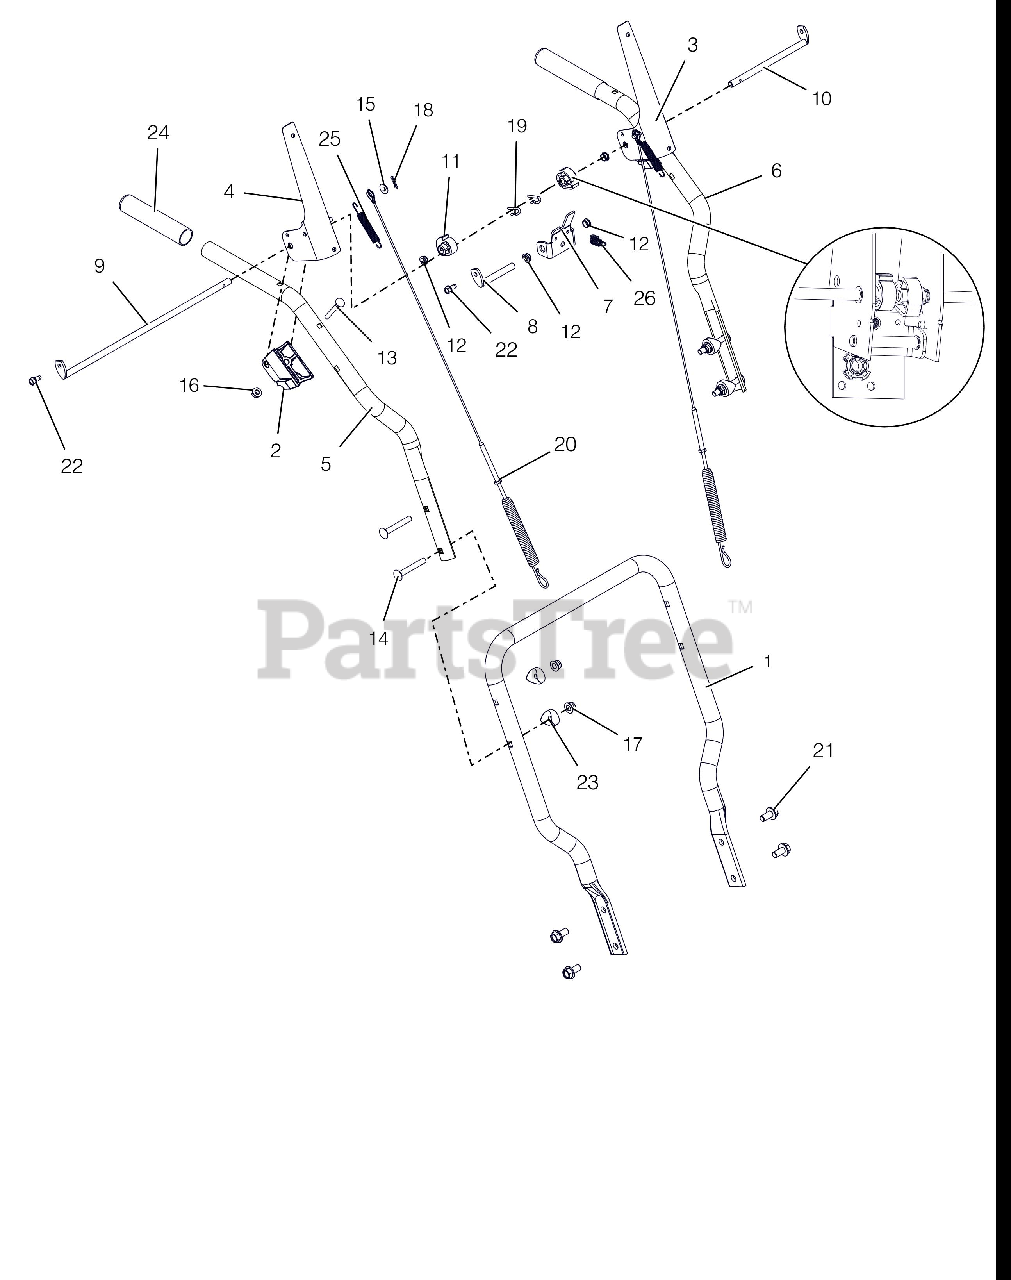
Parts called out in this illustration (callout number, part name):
1	HANDLEBAR, LOWER (COMPACT)
2	BLOCK, CLUTCH PADDLE
3	LEVER, CLUTCH-LH
4	LEVER, CLUTCH-RH
5	HANDLEBAR, UPPER - RH
6	HANDLEBAR, UPPER - LH
7	BRACKET, INTERLOCK ARM
8	ROD, PIVOT - INTERLOCK
9	ROD, PADDLE MOUNT - LONG
10	ROD, PADDLE MOUNT - SHORT
11	CAM, INTERLOCK
12	BUSHING, POLYLINER-.38 SNAPIN
13	BLT-RDHDXLSQNK .25-20X2.0 G5YZ
14	@BLT-RDHDSQNK .31-18X2.25 G5YZ
15	@WSHR-FL-STL.281X.62X.065 YWZC
16	@NUT-LK-TOP-FLG .25-20 YWZC
17	@NUT-LK-NYL-FLG .31-18 YWZC
18	PIN-HAIR INT .06X.18X.77
19	PIN, SPRING CLIP
20	CABLE, AUGER & UPPER TRACTION
21	BLT-SERHFWH .38-16X.75 YWZC
22	SCR-TAP .25-20X.50 HWH TR YWZ
23	SPACER, HANDLEBAR
24	HANDLE GRIP
25	SPRING, EXTENSION
26	SPRING-EXT .047X.438X1.45
